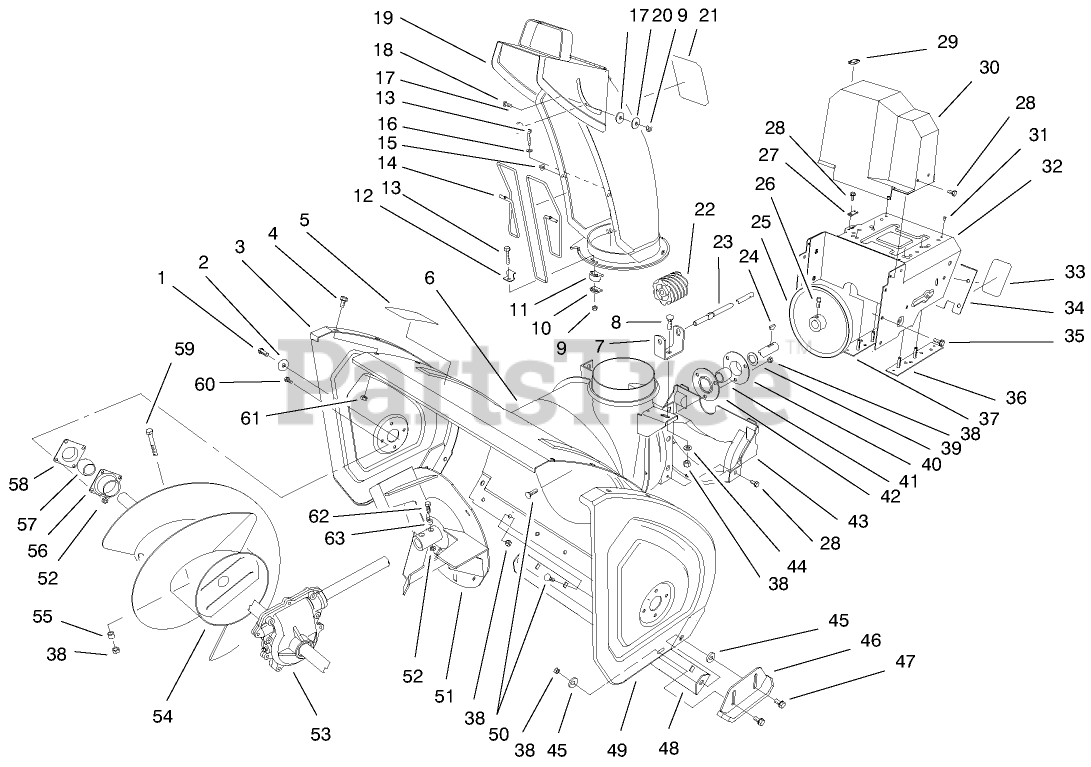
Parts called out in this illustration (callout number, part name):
1	SCREW-HH
2	WASHER
3	PLATE-SIDE, RH
4	SCREW-HHF
5	DECAL-WARNING, AUGER
6	HOUSING
7	BRACKET-WORM, CHUTE
8	BOLT-CARR
9	NUT-LOCK, NI
10	PLATE-RETAINER, CHUTE
11	RETAINER-CHUTE
12	CLIP-GUARD, CHUTE
13	SCREW-HSH
14	GUARD-CHUTE
15	NUT-PUSH
16	WASHER-FLAT
17	WASHER-PLASTIC
20	WASHER-FLAT
21	DECAL-DANGER
21	DECAL - DANGER
22	GEAR-WORM
23	ROD-CHUTE, LOWER
24	KEY-WOODRUFF
26	SCREW-SET, SQH
27	RETAINER-CABLE
28	SCREW-HWH
29	COVER-CABLE
30	COVER-BELT, UPPER
31	RIVET-POP
33	DECAL
34	COVER-FRAME, ENGINE
35	SCREW-HWHTF
36	LH FRAME PLATE ASM
37	RH FRAME PLATE ASM
38	NUT-LOCK, NI
39	WASHER-THRUST
40	FLANGE-CUP, BEARING
41	BEARING-BALL
42	FLANGE-CUP, BEARING
43	COVER-BELT, LOWER
44	WASHER-PLAIN
45	WASHER
46	SKID ASM
47	SCREW-HHF
48	BLADE-SCRAPER
49	PLATE-SIDE, LH
50	SCREW-CARR
51	IMPELLER ASM-4 BLADE
52	NUT-LOCK, NI
53	32IN AUGER GEARCASE ASM
54	AUGER ASM-RH, 32"
54	AUGER ASM-LH, 32"
55	SPACER-HUB, AUGER
56	BEARING-FLANGE, FRONT
57	BEARING
58	BEARING-FLANGE, REAR
59	SCREW-HH
60	SCREW-HH
61	NUT-LOCK, NI
62	SCREW-HHF
63	SPACER
